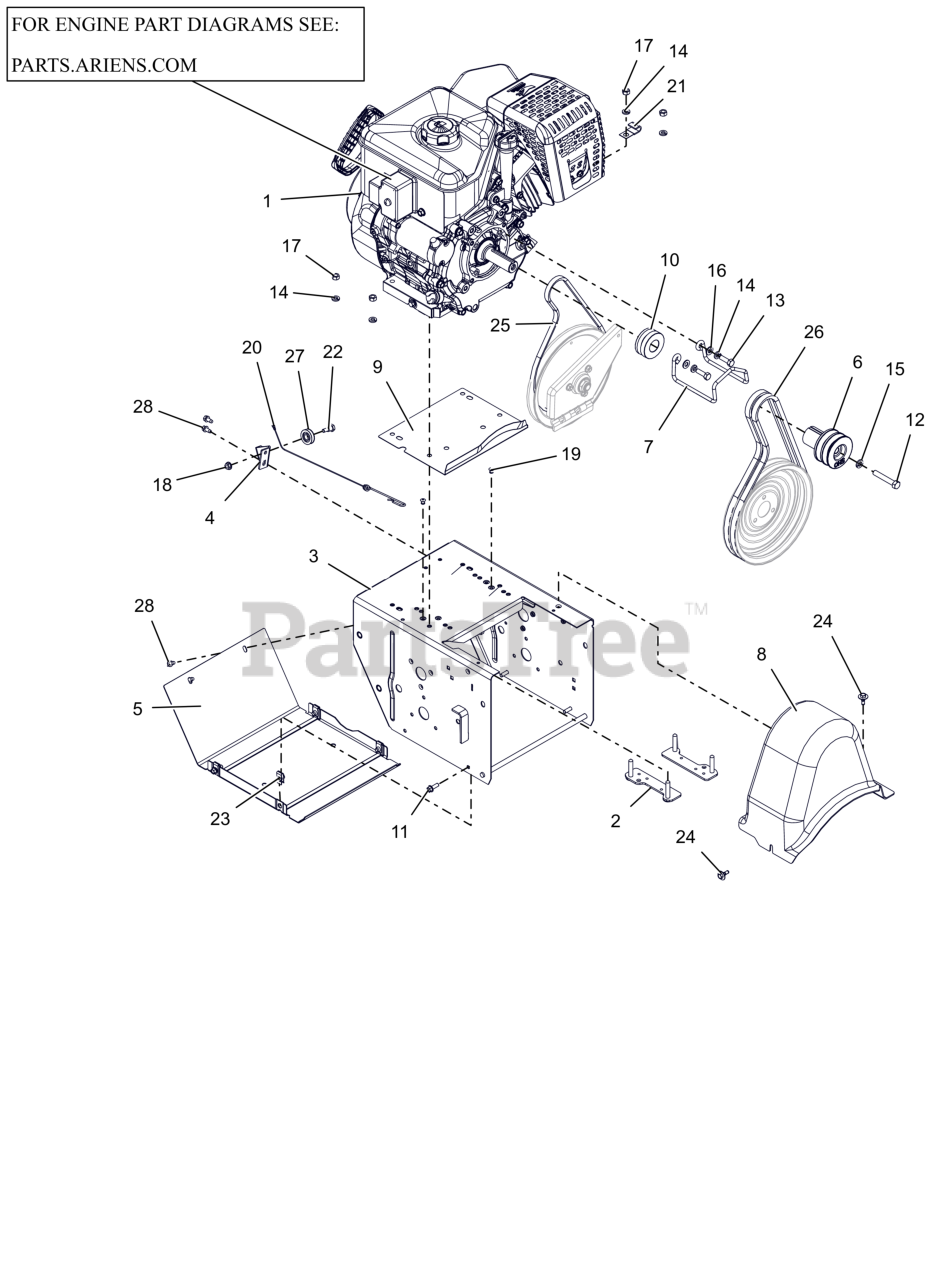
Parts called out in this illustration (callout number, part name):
1	ENGINE, EFI 369 GEN 3 240V/60W
2	STRAP, BOLT-LARGE
3	FRAME, MAIN - 14GA DELUXE (ORANGE)
4	BRACKET, CABLE PULLEY
5	COVER, BOTTOM
6	SHEAVE,ATTACHMENT-SHO 2 GRV
7	FINGER, BELT
8	COVER, BELT-LARGE
9	BAFFLE, WATER - LARGE BLOCK
10	SHEAVE, TRACTION (KEYLESS)
11	BLT, HWH .25-20X.75 G5 ZCC
12	BLT, HEX .38-24X2.25 G5 ZCC
13	BLT, HEX 0.3125-24X1 G5 ZCC
14	WSHR, LK-HVY .312X.097 ZCC
15	WSHR,LK-REG .375X.094 ZCC
16	WSHR,FLT .344X.688X.065 ZCC
17	NUT, HEX .312-18 ZCC
18	NUT-LK-TOP-FLG .250-20 GF ZCC
19	RVT, POP .1875 ZCC
20	CABLE, LOWER TRACTION,SS & PRO
21	J-CLAMP
22	BOLT, SHLDR -.375 X .375 X .25-20
23	NUT-RTNR .25-20X.56
24	SCR-TAP .25-20X.5 CAPTIVE
25	V-BELT, 3L-WRAPPED
26	V-BELT, HA-RAW EDGE (SET)
27	PULLEY, CABLE
28	SCR-TAP .25-20X.50 HWH ZCC
